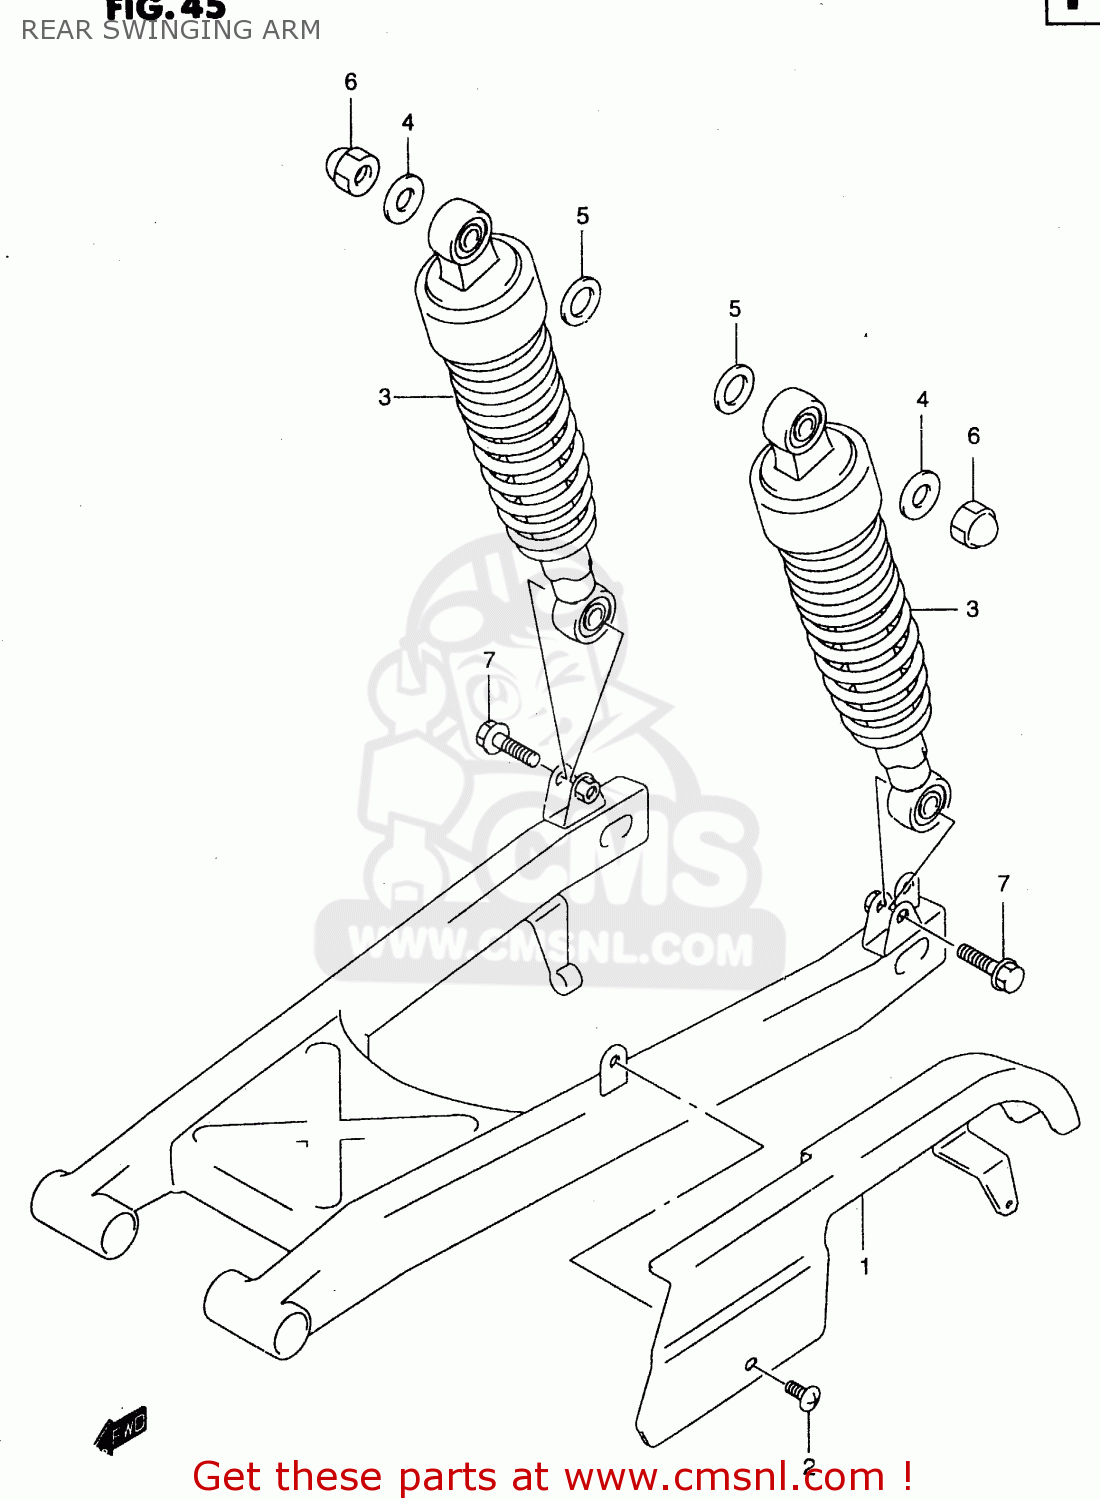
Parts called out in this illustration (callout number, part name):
1	SWINGINGARM ASSY,RR
2	BEARING(20X27X20)
3	SPACER,RR SWGARM PIVOT OUTER
4	SEAL,OIL(20X27X5)
5	SPACER,RR SWGARM PIVOT INNER
6	SEAL,OIL(20X27X5)
7	SHAFT,RR SWINGINGARM PIVOT
8	WASHER
9	NUT 14MM
10	BUFFER,CHAIN TOUCH DEFENSE
11	BOLT(6X20)
12	SPACER(6.5X9X3.8)
13	TORQUELINK,RR
14	BOLT(8X22.5)
15	BOLT(8X26.5)
16	WASHER,LOCK
17	NUT
18	PIN 20X20
19	ADJUSTER,CHAIN
20	PLATE,CHAIN ADJUSTER
21	NUT
